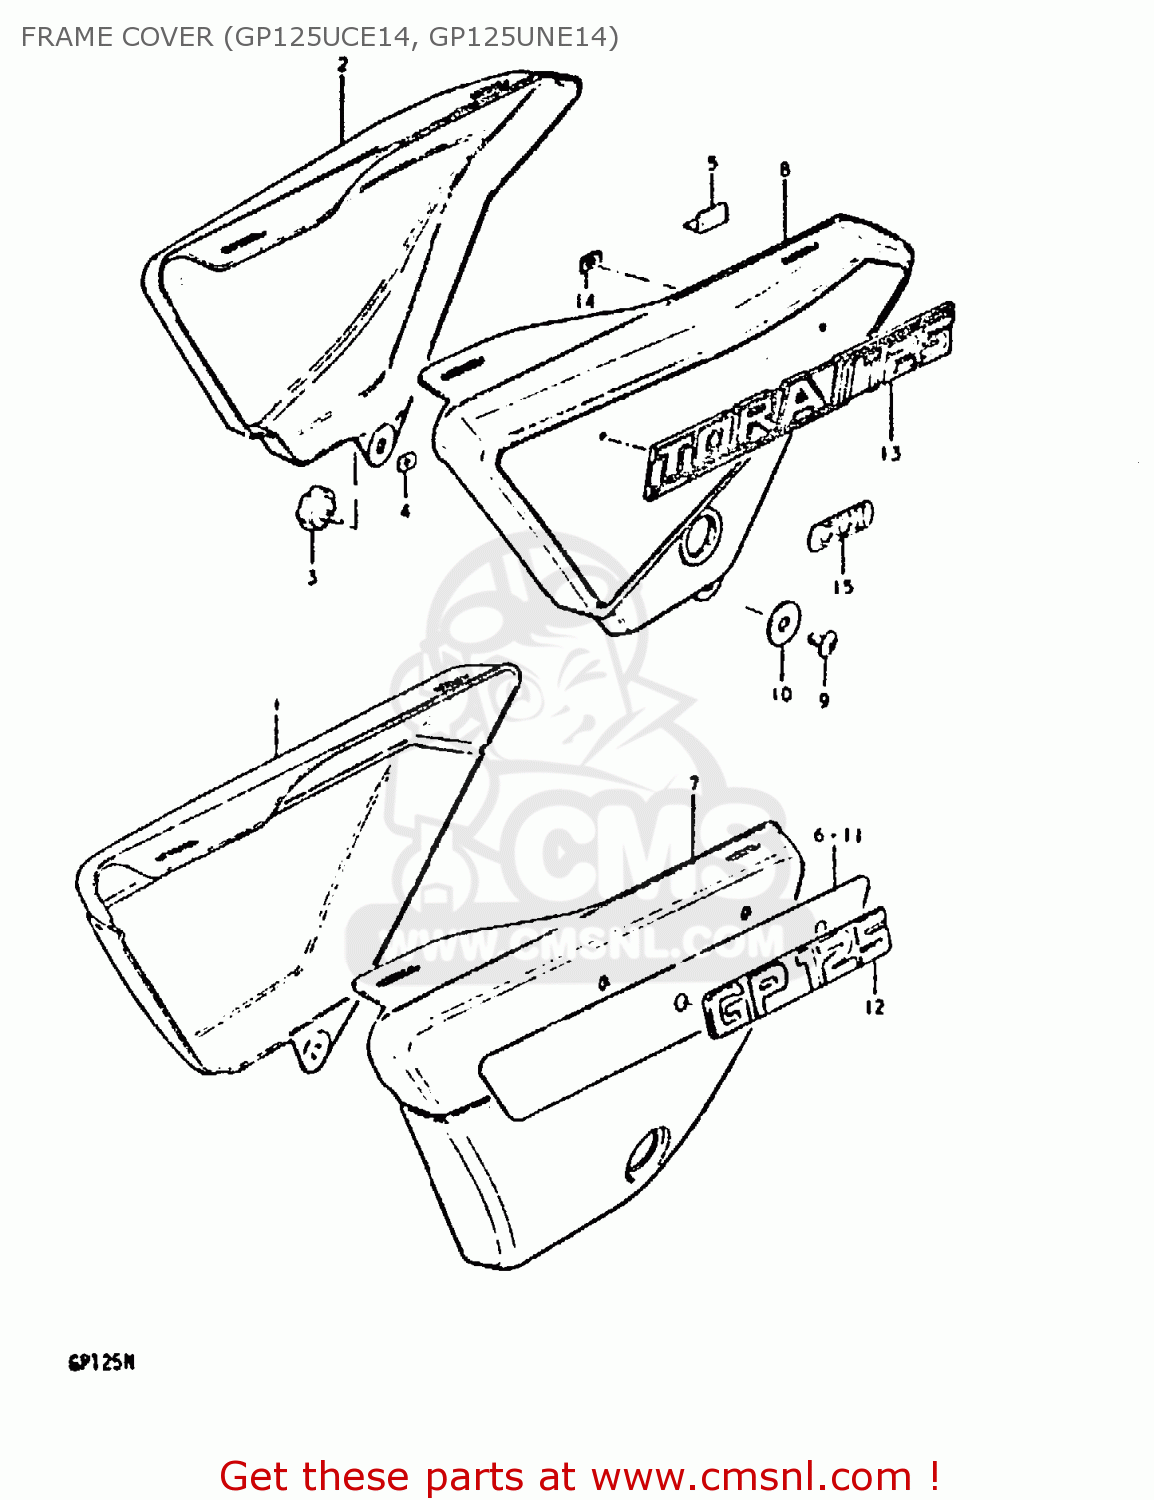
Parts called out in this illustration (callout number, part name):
2	COVER, FRAME RH
3	KNOB,FRAME COVER,R
4	NUT
5	CUSHION,FRAME COVER
8	COVER, FRAME LH
9	SCREW
10	WASHER
12	EMBLEM
13	EMBLEM
14	NUT
15	EMBLEM,CCIS
